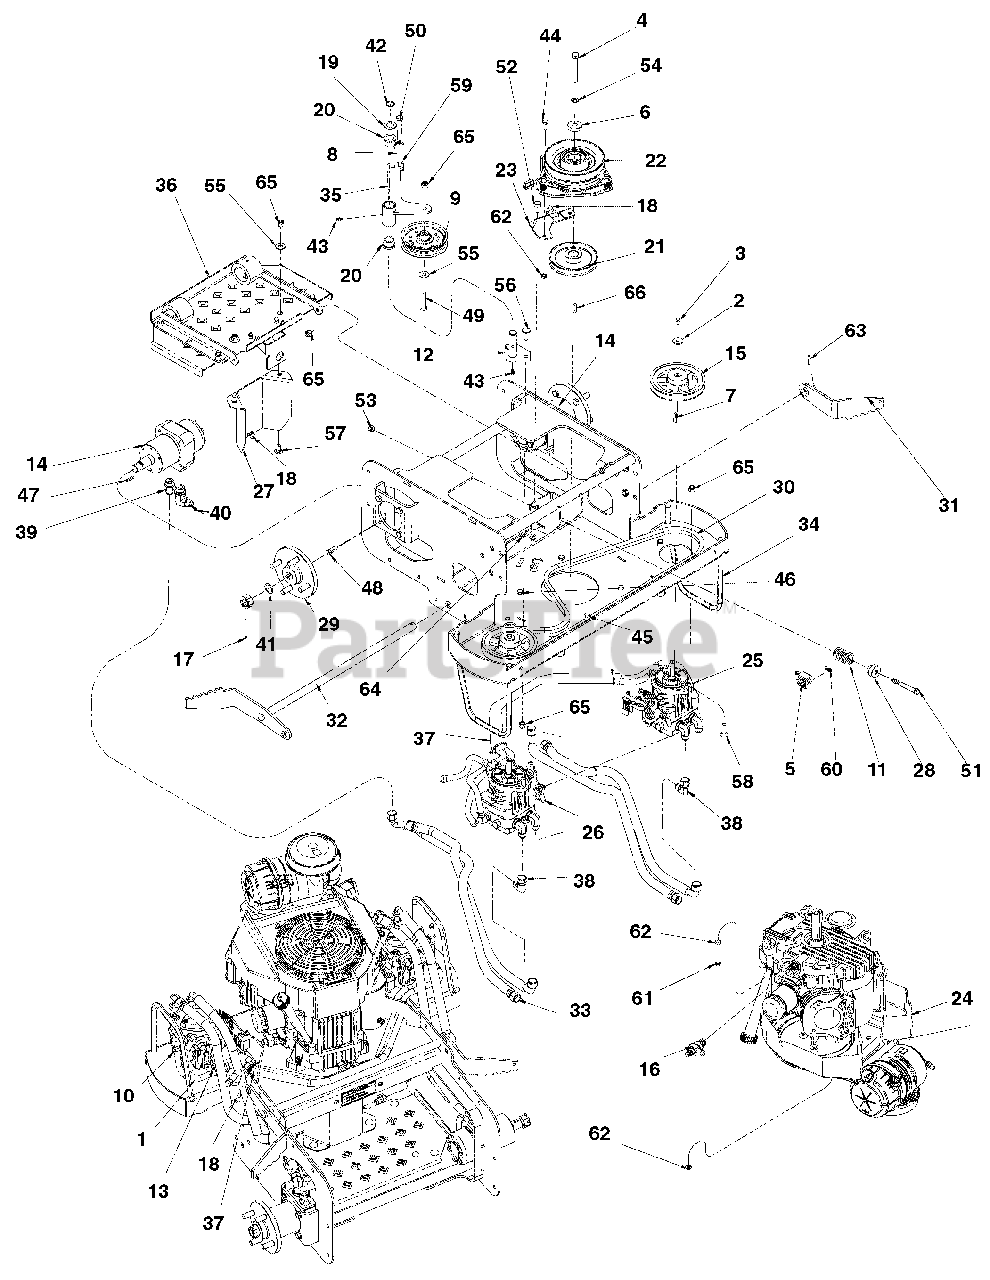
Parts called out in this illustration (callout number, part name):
1	Hose, 3/8 SAE30r7 Fuel & Oil
2	Washer, .250 Wide Heavy Flat Y
3	Bolt, M6 x 1.00 x 10 Hex 8.8 Y
4	Bolt, 7/16-20 x 3.00 Hex 5 Y
5	Switch (N.0.)
6	Spacer, .468 x 1.38 x .375 Y
7	Key, M5 x M5 x M30 RD
8	Spring, Ext .900 x .135x4.50 Y
9	Pulley, V-belt 4.00x.379 w/Bearing
10	Clamp, Hose - 1/2" Pinch
11	Spring, Com 1.22x.162x2.50 Y
12	Weldment, Pivot Idler Mount
13	Fitting, Tun 3/8 Hose
14	Motor, Wheel HGM-12p-7172
15	Assembly, Pump Pulley w/Set Screw
16	Fitting, Oil Drain
17	Pin, Cot .125 x 2.00 EXTP Y
18	Tie Wrap, Black
19	Bushing, Machine .750 x 1.25 x .048
20	Bearing, Flange .750 x 1.000 x .750 x 1.250
21	Pulley, V-belt 4.78pd x 1.000
22	Clutch Assembly, Ogura
23	Plate, Clutch Dog
24	Engine, Kawasaki 19hp FH580V
25	Assembly, Hyd Pump
26	Assembly, Hyd Pump
27	Cover, Operator Presence Control
28	Washer, Spring Y
29	Assy, Rear Wheel Hub
30	Belt, HA 68.2 EL AMD OHR
31	Weldment, RH Brake Arm
32	Weldment, LH Brake Shaft
33	Hose, Hyd 1/2 x 26 1/2 Ezflex
34	Weldment, Frame 34 w/Decals
35	Weldment, Idler Pivot
36	Assy, Foot Plate
37	Abrasion Sleeve
38	Adapter, .75 FESW x 3/4MJICX90
39	Adapter, Hydraulic Steel 7/8 "O" To .75
40	Adapter, 8MJ-10MB90
41	Shim, .020 x .787 x 1.102
42	Ring, Retaining-External .750 x .042
43	Grease Zerk, .25-28 Straight .69 LG
44	Bolt, Hex .31-18 x .75 Grade 5
45	Bolt, Hex .31-18 x 1.50 Grade 5
46	Bolt, Hex .31-18 x 1.75 Grade 5
47	Key, Woodruff .1875 x .75
48	Bolt, 3/8-16 x 1.00 Hex 5
49	Bolt, 3/8-16 x 1.75 Hex 5
50	Bolt, 3/8-16 x 2.50 Hex 5
51	Bolt, 3/8-16 x 3.25 Hex 5
52	Bolt, 7/16-14 x .750 Hex 5
53	Nut-Hex .31-18
54	Washer, .375 Medium Spring Lock Y
55	Washer-Flat-Steel .438 x 1.00 x .083
56	Bolt, Round Head Square Neck .38-16x1.00 G 5
57	Bolt, Round Head Square Neck .38-16x1.00 G 5
58	Bolt, Round Head Square Neck .38-16x1.25 G 5
59	Nut, .38-16 Jam Grade 5
60	Nut-Locking-Nylon 10-24 with Insert
61	Nut-Jam .312-18
62	Nut-Locking-Nylon .312-18
63	Pin-Roll .156 x 1.00
64	Screw, Machine 10-24 x .625 Panhead
65	Nut-Locking-Nylon .38-16
66	Key, .250 x .250 x .995 TPR
